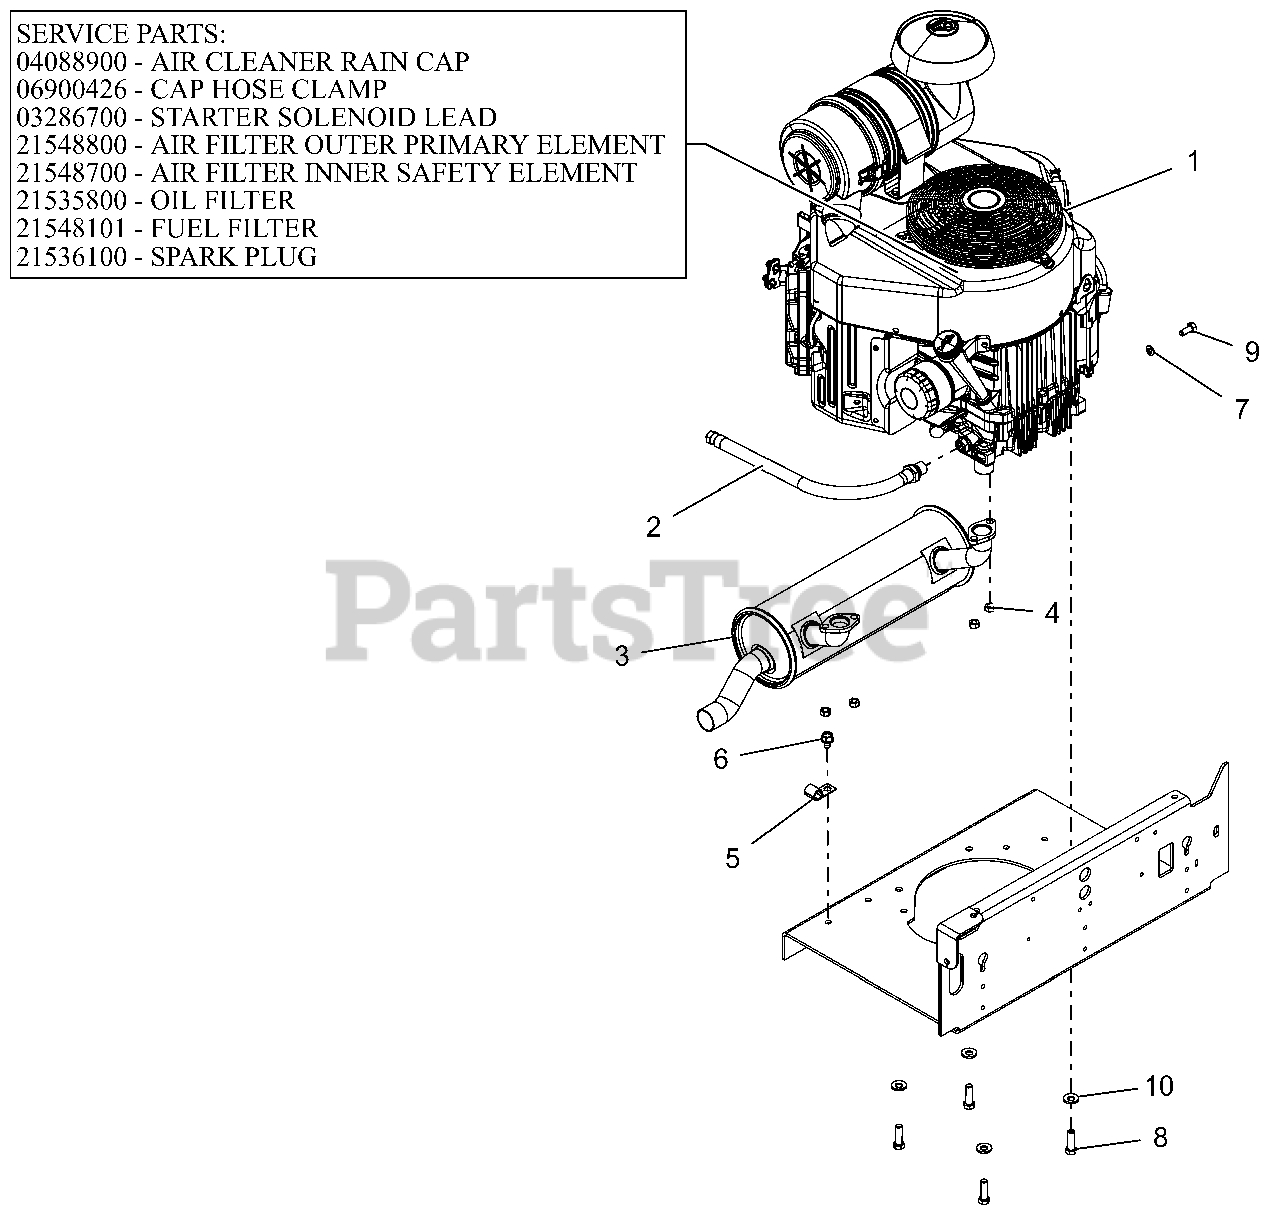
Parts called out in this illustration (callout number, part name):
1	ENGINE, KAWASAKI FX730
1	CAP, KAW 11065-7025
1	CLAMP, HOSE #36 SS 1.813-2.75
1	LEAD - STARTER SOLENOID
1	FILTER, OUTER
1	FILTER, INNER - KAW
1	FILTER,OIL - KAW
1	FUEL FILTER-KAWASAKI FR
1	PLUG, SPARK
2	HOSE, OIL DRAIN
3	MUFFLER, KAW FX691/730
4	NUT-LK-TOP M8-1.25 YWZC
6	@SCR-TAP .38-16X.50 HWH TR YWZ
7	@WSHR-LK .31X.078 REG YWZC
8	BLT-HEX.38-16X1.25 G5YZ NYTORQ
9	@BLT-HEX M8-1.25X20 YWZC
10	WASHER, 3/8" SPRING DISC
